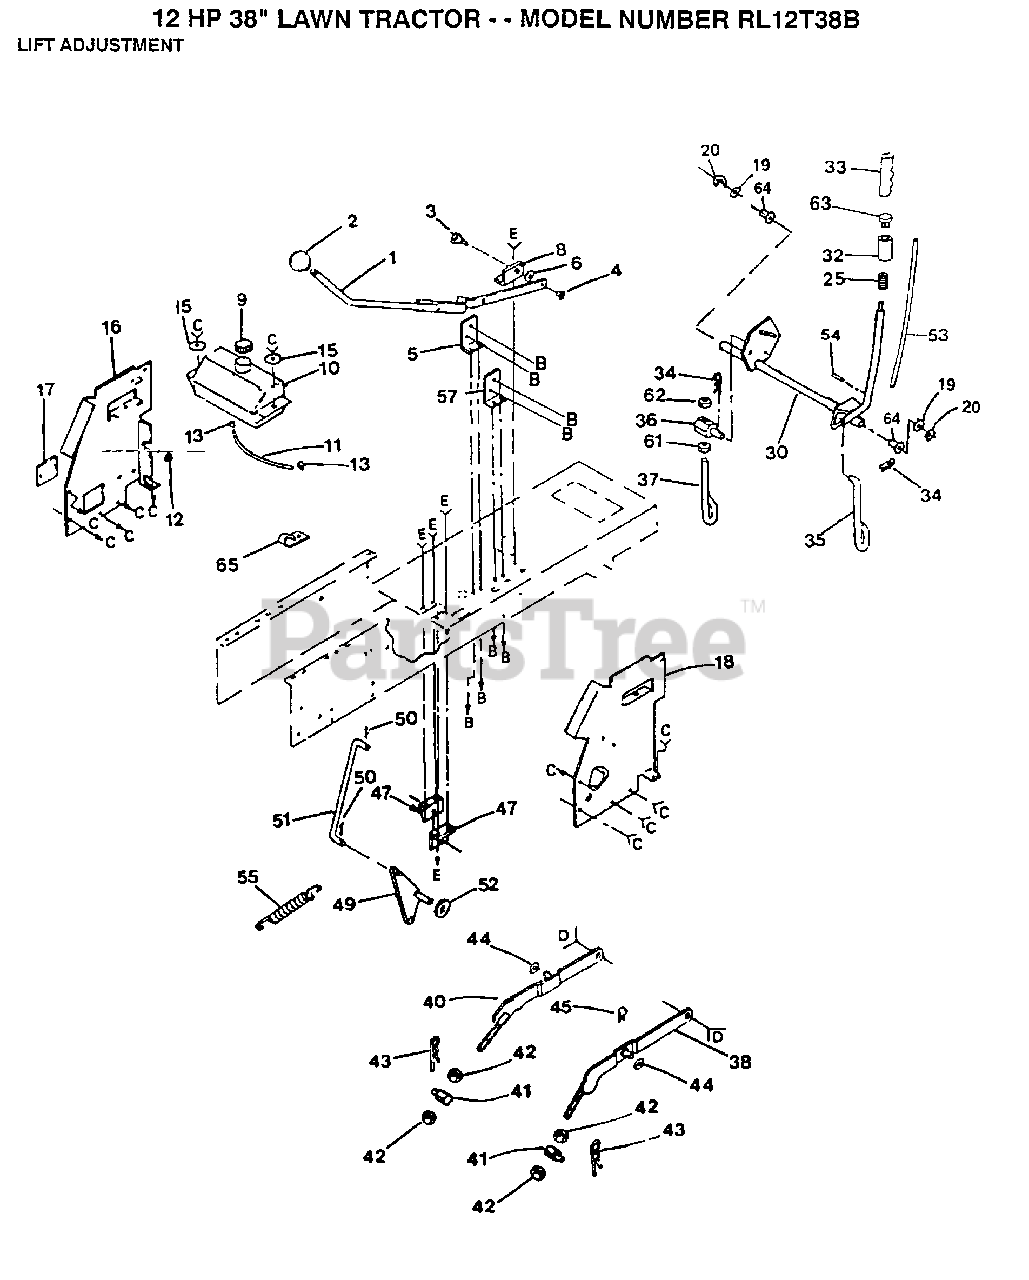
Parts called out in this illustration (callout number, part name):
3	"BOLT, SHOULDER LT"
5	"BRACKET,SWITCH LT"
7	SCREW
8	"SUP,LVR,CLUTCH LT"
10	TANK.FUEL.LT.
11	FUEL LINE T
12	SNAP BUSHING T
13	HOSE CLAMP
14	SCREW
15	WASHER GT
16	PANEL DASH LH
17	COVER ACCESS
19	WASHER
33	GRIP
35	LIFT LINK LT
37	PIVOT PIN T
38	RH SUSP ARM ASM
39	"BOLT, SHOULDER LT"
40	LH SUSP ARM ASM
42	NUT
43	SPRING H
45	SPRING.RETAINER
47	"BRKT,BELLCRAN T"
49	"T, BELLCRANK"
50	COTTER PIN
52	WASHER
54	PIN-GROOVE LT
57	BRACKET LT
59	WASHER T
60	NUT SPECIAL T
61	NUT
64	NYLON BEARING
65	INSUL CLIP T
